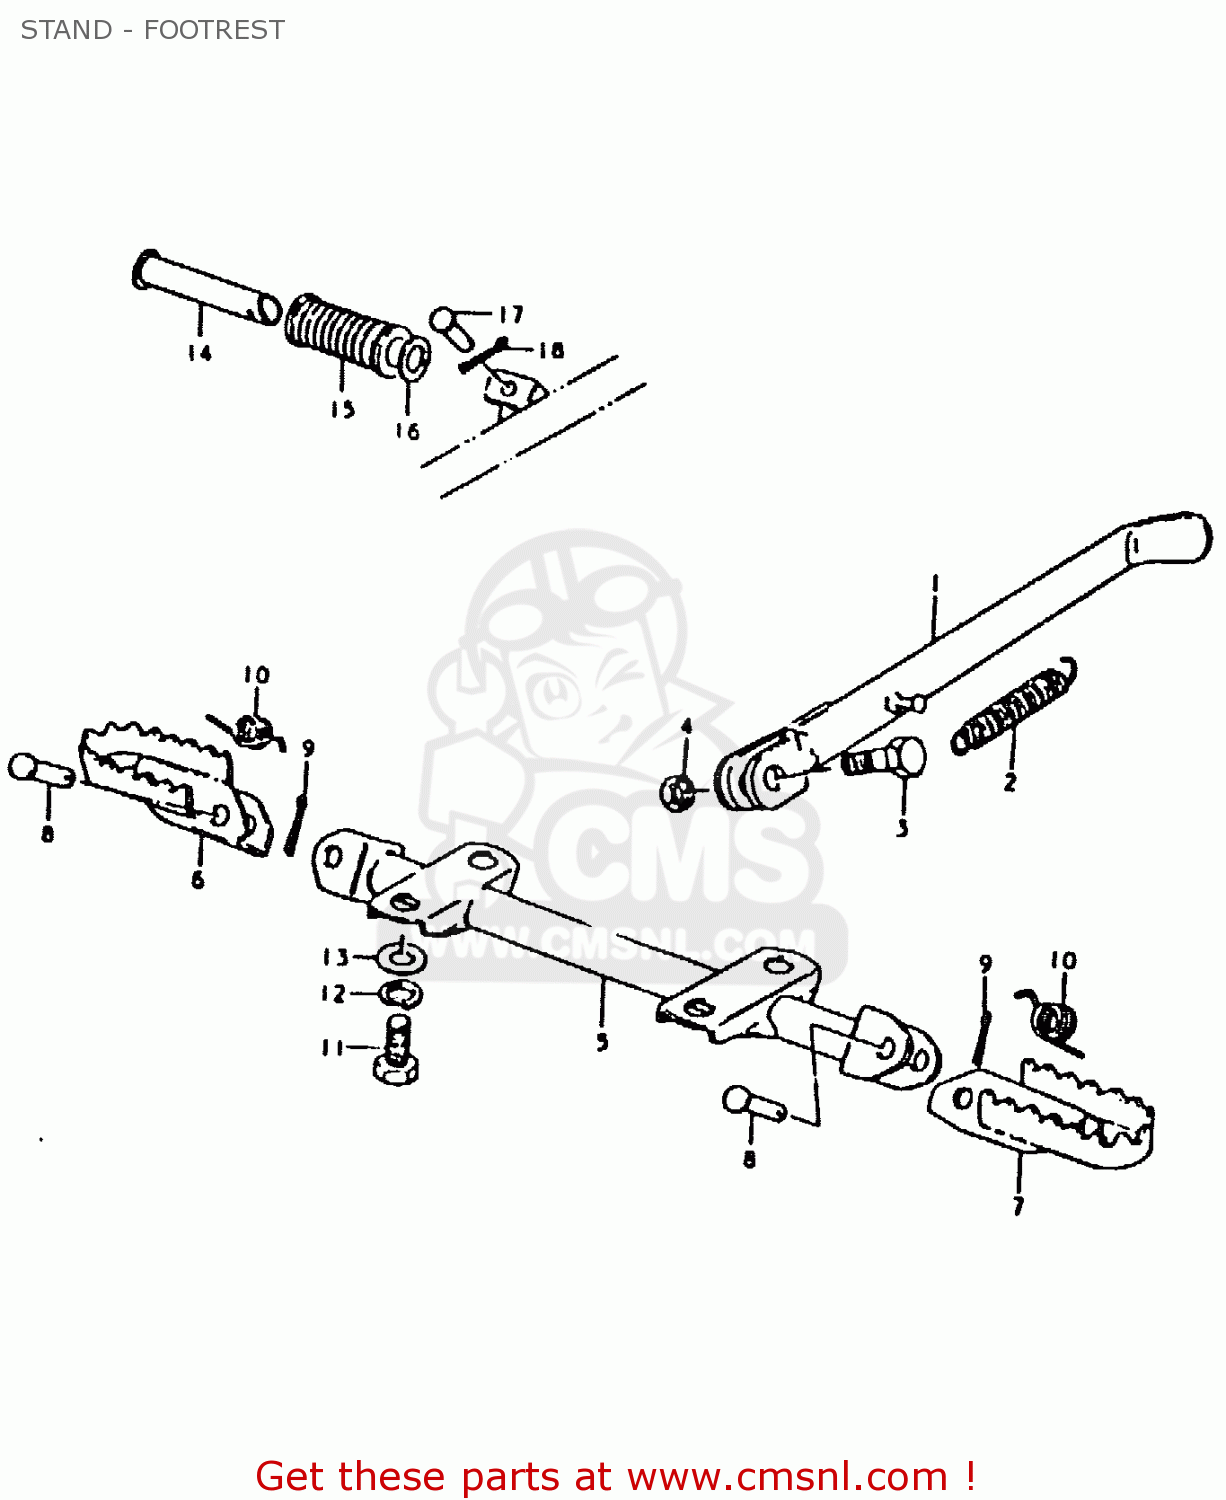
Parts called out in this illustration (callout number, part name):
1	STAND,PROP
2	SPRING
3	BOLT(10X30)
4	NUT
5	BAR,FR FOOTREST
6	FOOTREST,FRONT
7	FOOTREST
8	PIN
9	PIN 20X20
10	SPRING
11	BOLT
12	LOCK WASHER
13	WASHER
14	BAR,FOOTREST RUBBER
15	RUBBER,PILLION FOOTREST
16	WASHER (19.5X32X2)
17	PIN
18	PIN 20X20
